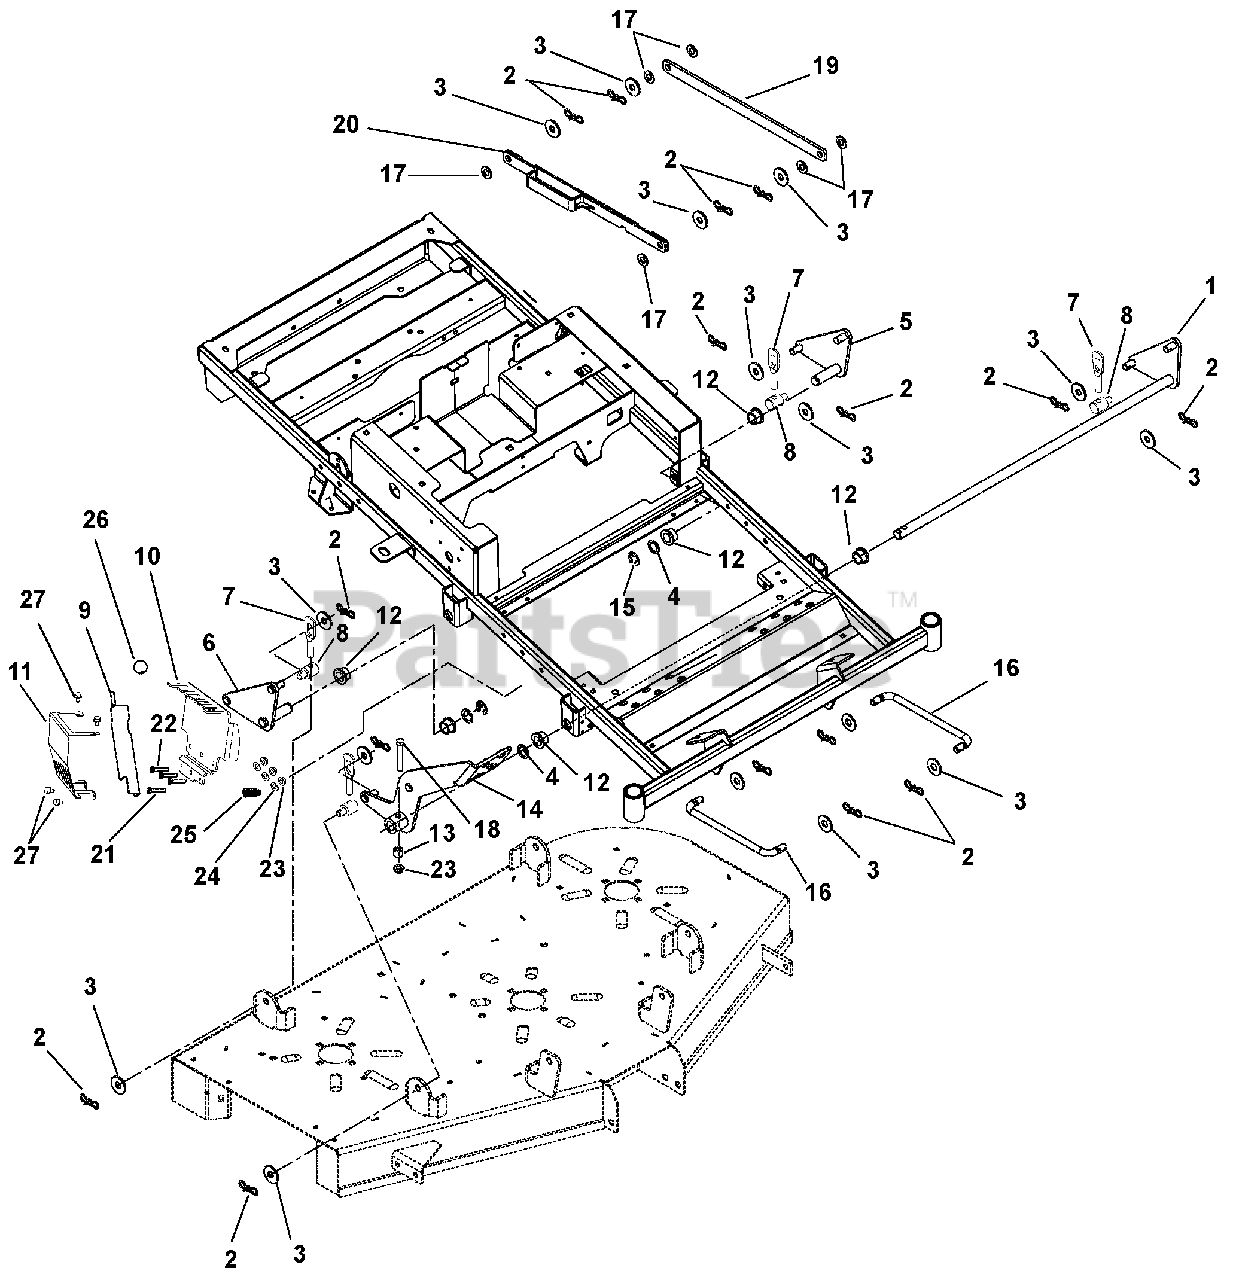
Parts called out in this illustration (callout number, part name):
1	Weldment, Deck Pivot Front
2	Pin, Bow Tie Locking Cotter .091 x 1.875
3	Washer, Flat Steel.511 x 1.441 x .125
4	Washer, Flat Steel .754 x 1.125 x .062
5	Weldment, Deck Pivot ZTXL Rear Left Hand
6	Weldment, Deck Pivot ZTXL Rear Right Hand
7	Deck Link
8	Trunnion .50
9	Lever, Weldment HOC XL
10	Bracket, HOC XL
11	Guard, Plate Styled HOC
12	Bushing, Flange .750 x 1.000 x .625 x 1.250
13	Bushing, Sleeve .391 x .688 x .52
14	Weldment, ZTXL Foot Pedal
15	Ring, Retaining-External .750 x .050
16	Link, Drag
17	Washer, Flat Nylon .52 x 1.00 x .08
18	Bolt, Hex .38-16 x 2.50 Grade 5
19	Link, Lift
20	HOC, Link Retaining XL
21	Bolt, Hex .38-16 x 2.25
22	Bolt, Hex .38-16 x 1.75 Grade 5
23	Nut .38-16 Nyloc Flange
24	Washer, Flat Steel .38 x .875 x .083
27	Screw, Tapping Hex Washer Head Thread Rolling .25-20 x .50 YWZ
